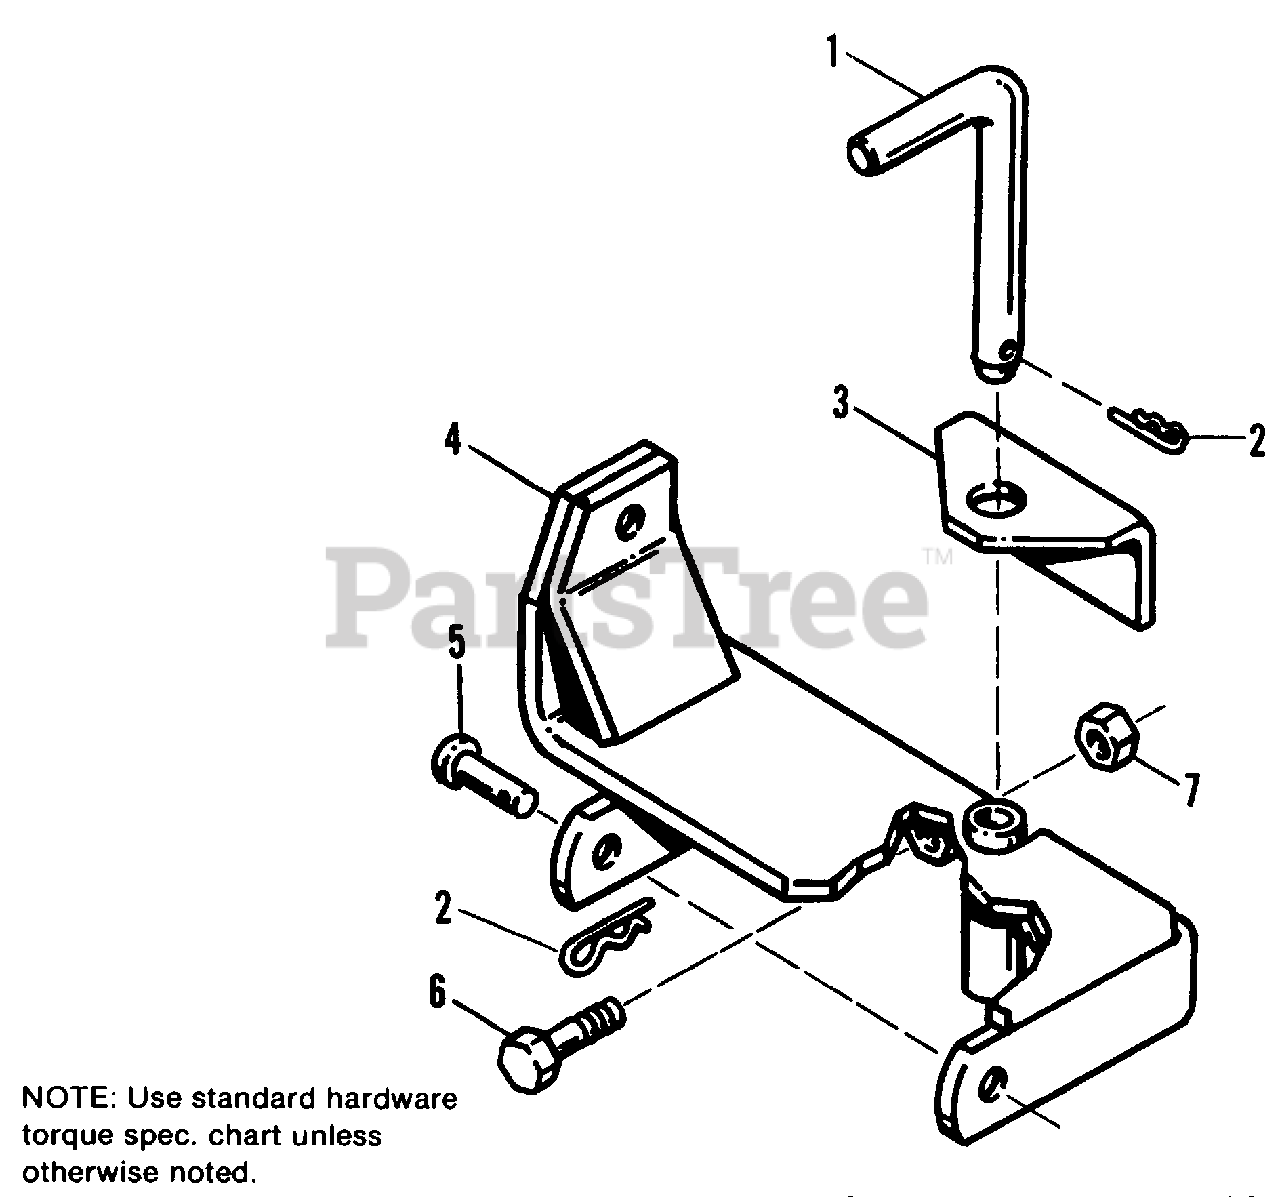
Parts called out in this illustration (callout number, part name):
2	CLIP, Spring
3	PLATE, Stabilizer
4	CLEVIS & LIFT ARM ASSY.
6	CAPSCREW, Hex Hd., 5/8-11 x 2-1/4
7	NUT, Hex, Jam, 5/8-11
